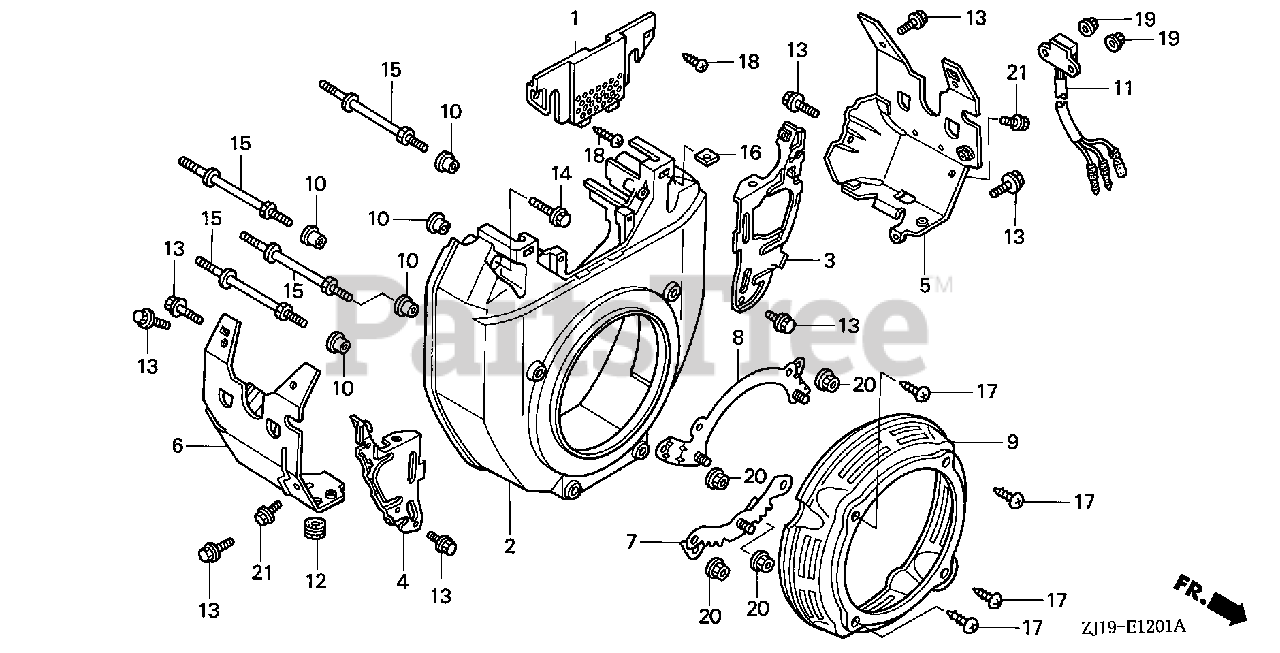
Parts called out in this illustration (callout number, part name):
1	COVER, FUEL PUMP (MANUAL CONTROL)
2	COVER, FAN *R8* (RECOIL STARTER) (BRIGHT RED)
3	PLATE, R. SIDE
4	PLATE, L. SIDE
5	SHROUD, R. (OIL ALERT)
6	SHROUD, L.
7	STAY A, RECOIL STARTER
8	STAY B, RECOIL STARTER
9	COVER, RECOIL STARTER STAY *R8* (BRIGHT RED)
10	COLLAR B, TAILLIGHT
11	ALERT UNIT ASSY., OIL
12	RUBBER, RR. FENDER CUSHION
13	BOLT, FLANGE (6X12) (CT200)
14	BOLT, FLANGE (6X23)
15	BOLT, STUD (6X71)
16	NUT, SQUARE (5MM)
17	SCREW, TAPPING (5X16)
18	SCREW, TAPPING (5X20)
19	NUT, FLANGE (5MM)
20	NUT, FLANGE (6MM)
21	BOLT, FLANGE (6X8)
